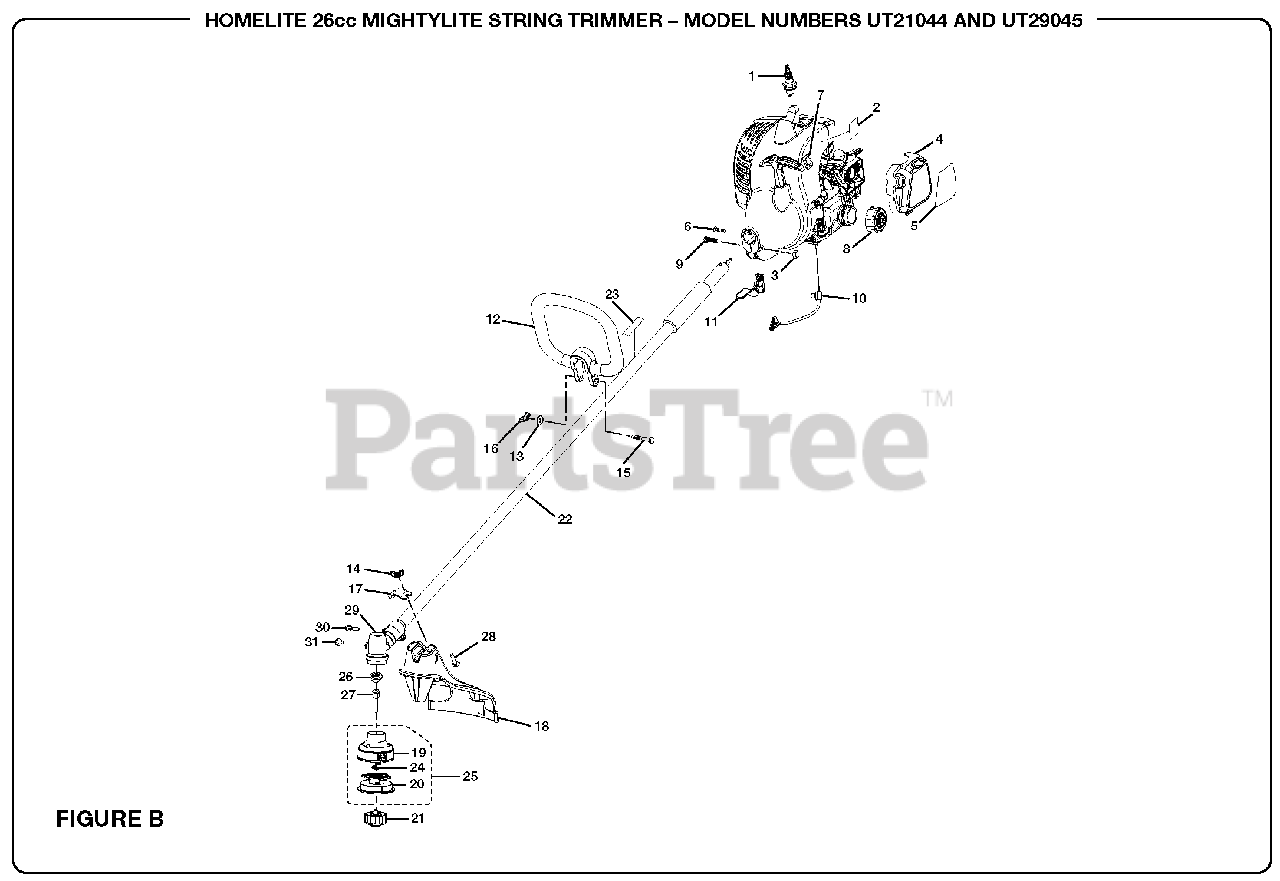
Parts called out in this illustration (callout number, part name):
1	Spark Plug (Champion RCJ6Y)
2	Logo Label
3	Hex Nut (M6)
4	Air Box Cover
5	Starting Label
6	Screw (8-16 x 5/16 in.)
7	Switch
9	Bolt (M6 x 20 mm)
10	Throttle Cable
11	Throttle Trigger
13	Washer (1/4-20)
14	Wing Nut (1/4-20)
15	Bolt (1/4-20 x 40 mm)
16	Wing Nut (1/4-20)
17	Mounting Bracket
18	Straight Shaft Grass Deflector
19	Large String Head Housing
20	Dual Line Spool and String
21	Spool Retainer
22	Boom Assembly
23	Warning Label
24	Spring
25	String Head Assembly
26	Flanged Washer
28	Screw (1/4-20 x 1 in., Sq. Hd.)
29	Gear Head
30	Bolt (1/4-20 x 1-1/4 in.)
31	Screw (10-24 x 5/8 in.)
